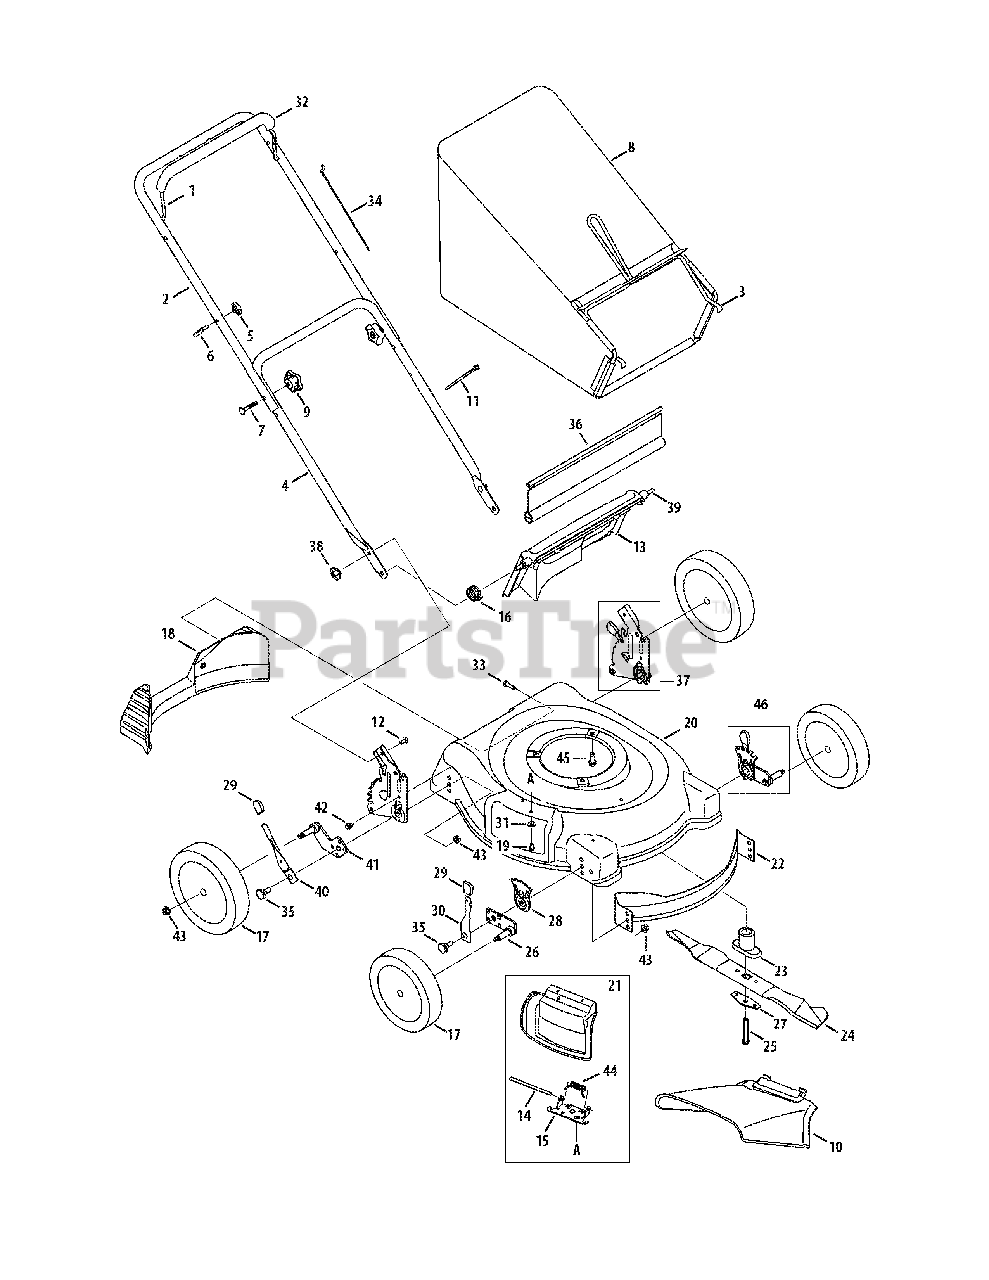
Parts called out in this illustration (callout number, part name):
1	Blade Control Handle
6	Rope Guide
7	Carriage Bolt ,5/16-18 x 2
8	Grass Bag
9	Hand Knob
10	Side Chute
11	Cable Tie
12	Carriage Bolt ,1/4-20
13	Rear Discharge Door
14	Hinge Pin
15	Deflector Chute Adaptor
16	Torsion Spring - RH
17	Wheel
18	Rear Baffle
19	Screw, 1/4-20 x .500
20	Deck - 21"
21	Hinged Mulch Plug Assembly
22	Front Baffle
23	Blade Adapter, 25mm x 2.15
24	Mulching Blade
25	Hex Screw , 3/8-24 x 2.5
26	Pivot Arm Assy RH (8" wheel)
26	Pivot Arm Assy LH (8" wheel)
27	Blade Bell Support
28	Front Adjustment Plate
29	Adjustment Lever Knob
30	Spring Lever Assembly
31	Bell Washer
32	Bail Cover
33	Screw, 1/4-15 x 1.000
34	Control Cable 40"
35	Shoulder Screw
36	Trail shield
37	Rear Handle Bracket Assy. - LH
37	Rear Handle Bracket Assy. - RH
38	Wing Nut, 1/4-20
39	Rear Door Pivot Rod
40	Spring Lever
41	Pivot Arm Assembly - RH
41	Pivot Arm Assembly - LH
43	Flange Lock Nut, 3/8-16
44	Torsion Spring
45	TT Sems Screw, 3/8-16 x 1.0
46	Ht. Adj. Assy. Front LH (8" wheel)
46	Ht. Adj. Assy. Front RH (8" wheel)
